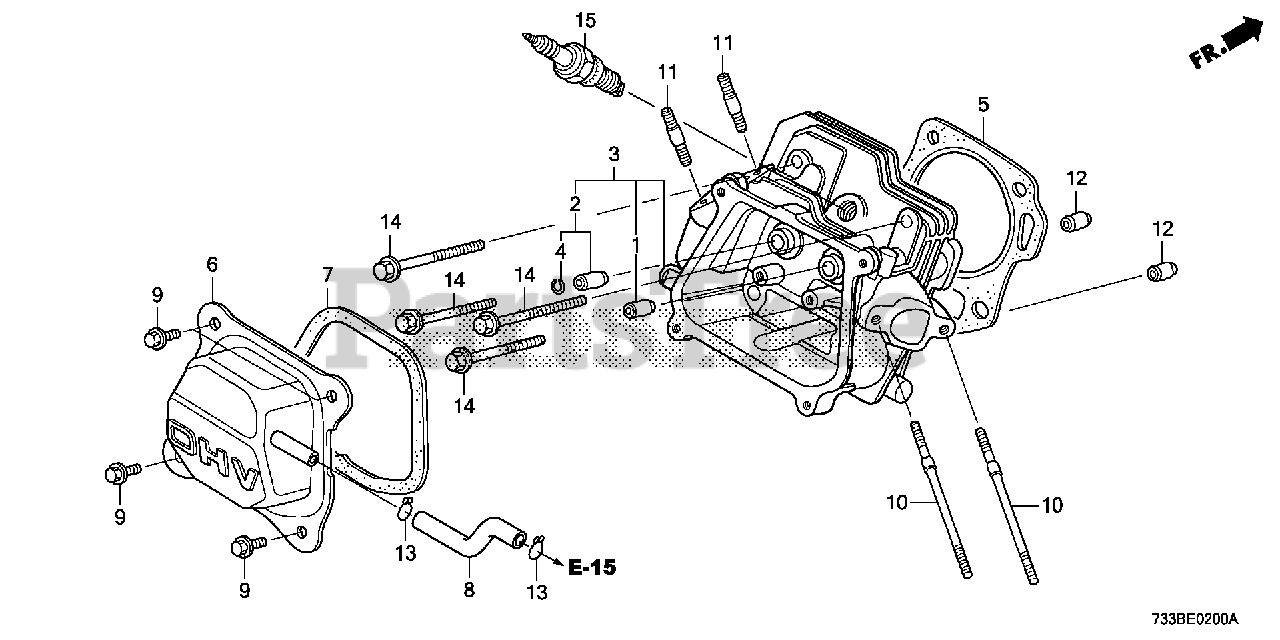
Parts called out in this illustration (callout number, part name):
1	GUIDE, VALVE (OVER SIZE)
2	GUIDE, EX. VALVE (OVER SIZE)
3	CYLINDER HEAD
4	CLIP, VALVE GUIDE
5	GASKET, CYLINDER HEAD (NIPPON LEAKLESS)
6	COVER, HEAD
7	GASKET, HEAD COVER
8	TUBE, BREATHER
9	BOLT, FLANGE (6X12) (CT200)
10	BOLT, STUD (6X112)
11	BOLT, STUD (8X32)
12	PIN, DOWEL (10X16)
13	CLIP, TUBE (C12)
14	BOLT, FLANGE (8X60)
15	SPARK PLUG (BPR5ES) (NGK)
15	SPARK PLUG (W16EPR-U) (DENSO)
15	SPARK PLUG (BPR6ES) (NGK)
15	SPARK PLUG (W20EPR-U) (DENSO)
